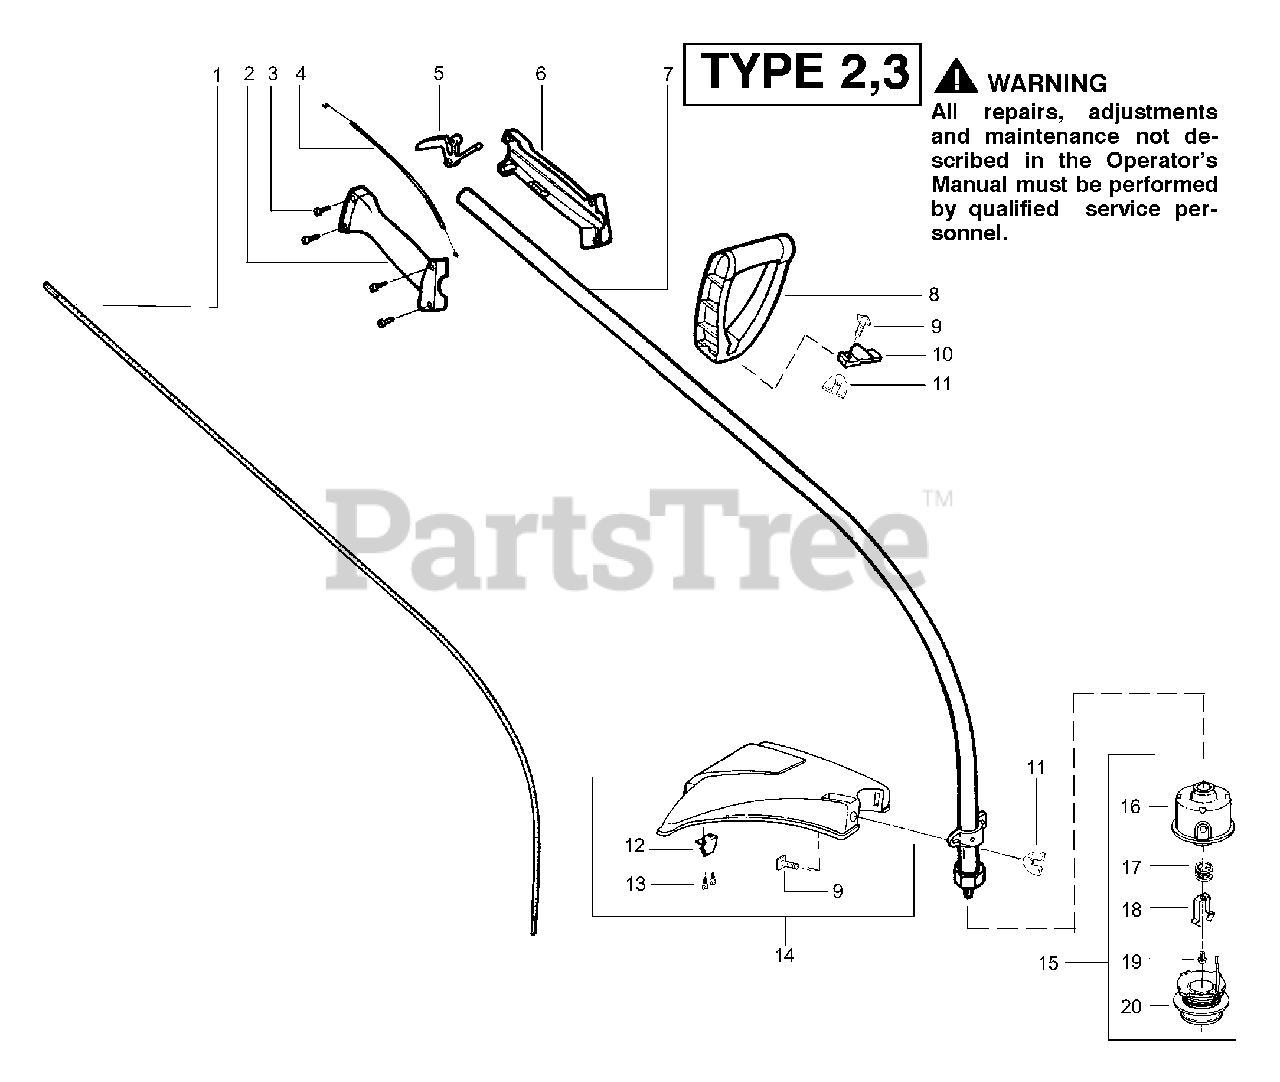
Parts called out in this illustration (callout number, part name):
1	Shaft-Flex
2	Throttle Hsg. (Right)
3	Screw-Throttle Hsg.
4	Kit-Throttle Cable Ass'y.
6	Throttle Hsg. (Left)
7	Drive Shaft Hsg. Ass'y
8	Assist Handle
9	Bolt-Handle/Shield
10	Clamp-Handle Assist
11	Wingnut-Handle/Shield
12	Line Limiter
13	Screw-Line Limiter
14	Kit-Shield Ass'y.
15	Accy-Cutting Head Ass'y.
16	Assy-Hub
17	Spring-Compression
18	Clip-Retainer-Head
19	Screw w/ Washer-Head
20	Accy-Spool w/Line
